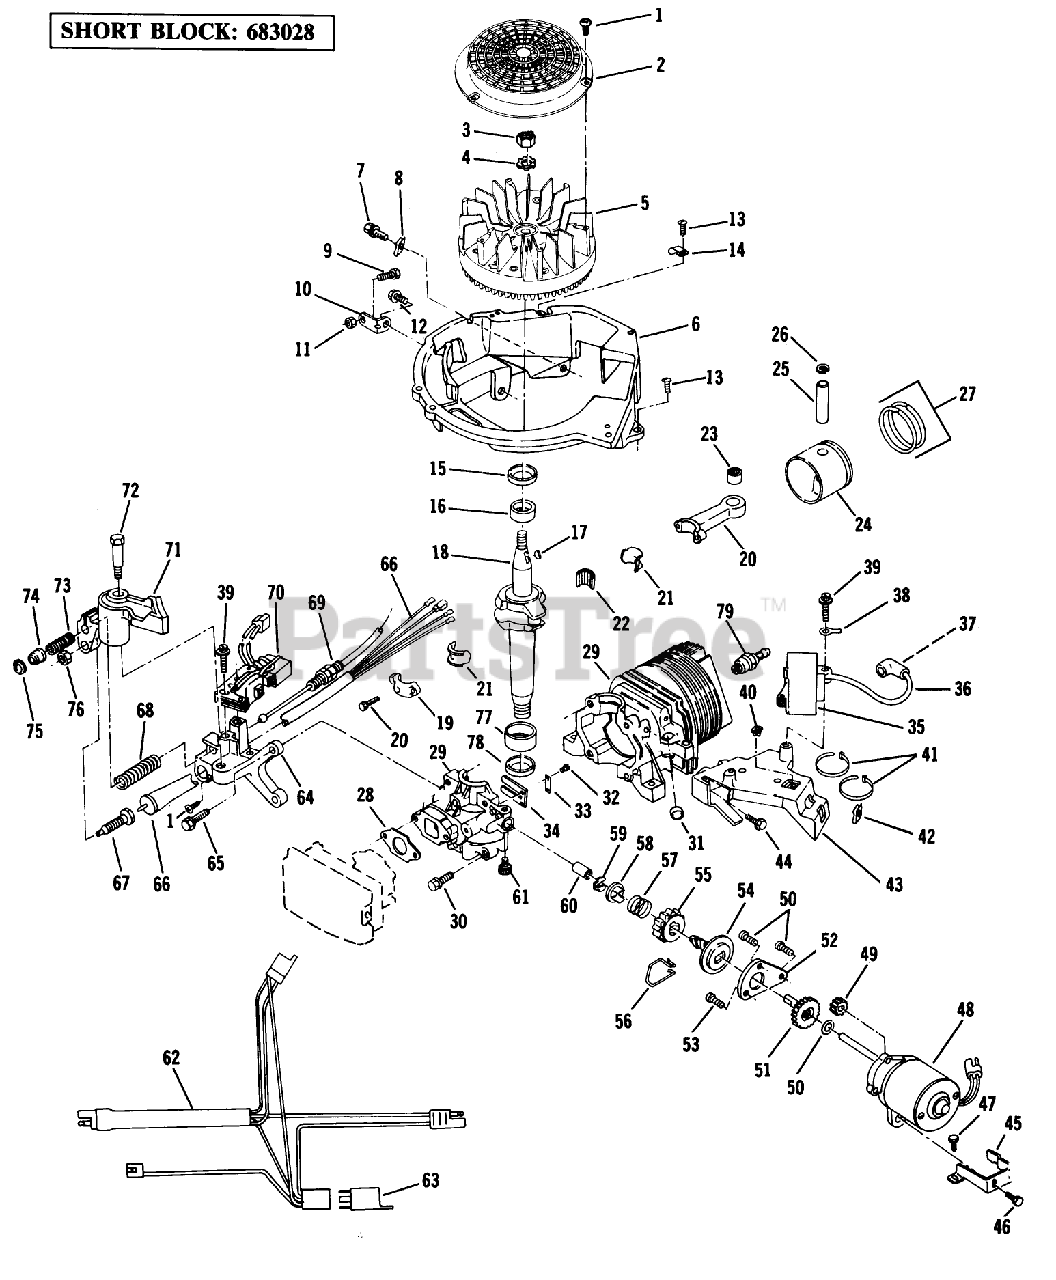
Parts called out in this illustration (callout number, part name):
1	SCREW F
2	SCREEN F'WHEEL S
3	NUT
6	BASE SHROUD F
7	SCREW-SEMS
9	BOLT F
11	NUT-LOCK F
13	SCREW F
16	BEARING V
17	KEY
20	SCREW-HSH
21	LINER ASM
23	BEARING AY F
26	RING-RETAINING
28	GASKET CARB S
30	SCREW S
31	PLUG-CORE VF
33	PLATE-BACKUP, REED
36	HT LEAD&COVER XEV
38	TERMINAL S
40	NUT-CLIP
42	NUT - SPEED S
45	BRACKET
46	SCREW
49	*PINION EF
51	GEAR-DRIVEN
53	SCREW EF
55	PINION EF
56	SPRING F
57	*SPRING PINION EF
59	RET.RING EF
60	SLEEVE F
64	BRACKET F
67	PLUNGER S
68	SPRING-BRAKE
69	CONTROL CABLE
73	SPRING
74	ACTUATOR-LEVER, BRAKE
75	RETAINER S
77	BEARING V
78	SEAL-OIL
